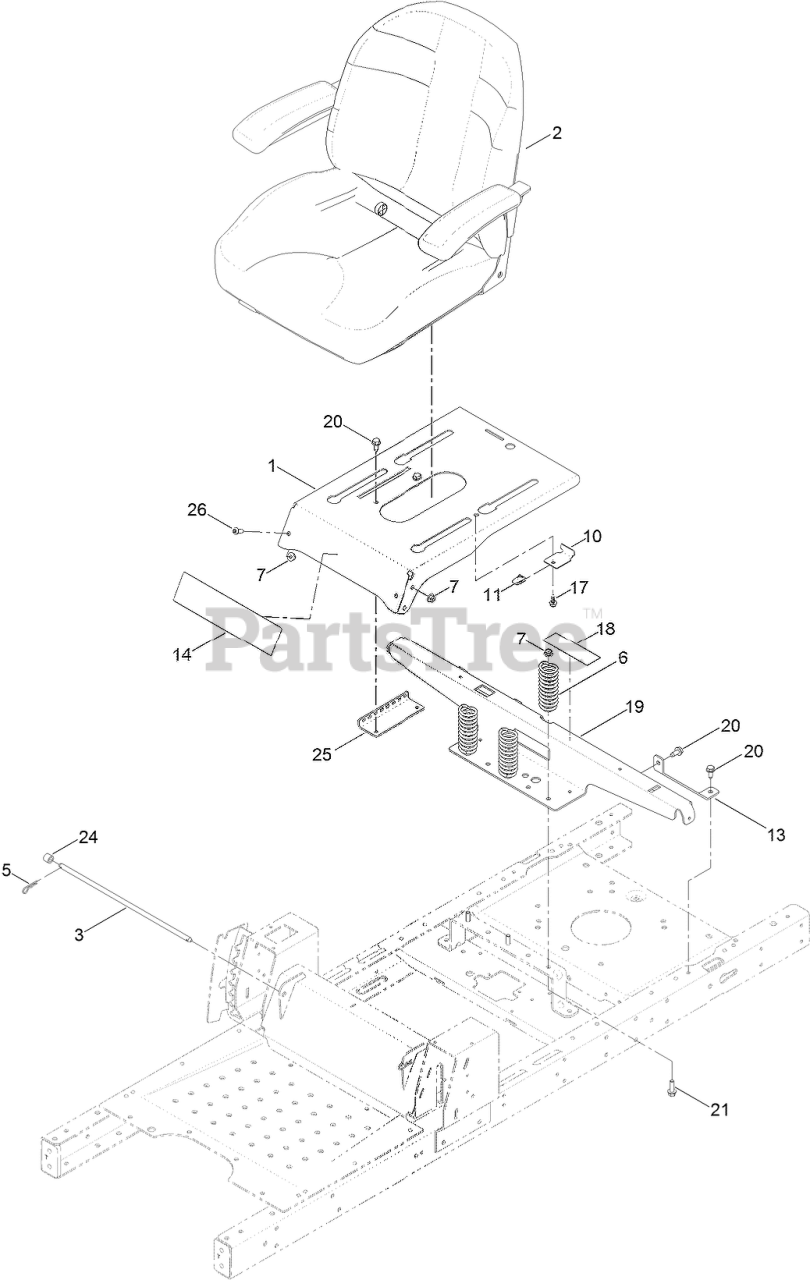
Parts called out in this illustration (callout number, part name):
1	PAN-SEAT
2	SEAT ASM
3	ROD-STOP
5	PIN-COTTER
6	SPRING-COMPRESSION
7	NUT-HF, NI
10	BRACKET-STOP, SEAT
13	SUPPORT-TANK, REAR
17	SCREW-HHF
18	DECAL-SERVICE, CE
19	SUPPORT-POD, WIDE
20	SCREW-HWHTF
21	SCREW-HHF
24	BUSHING-LEVER, LIFT
25	BRACKET-LATCH, SEAT
26	SCREW-HSBH
